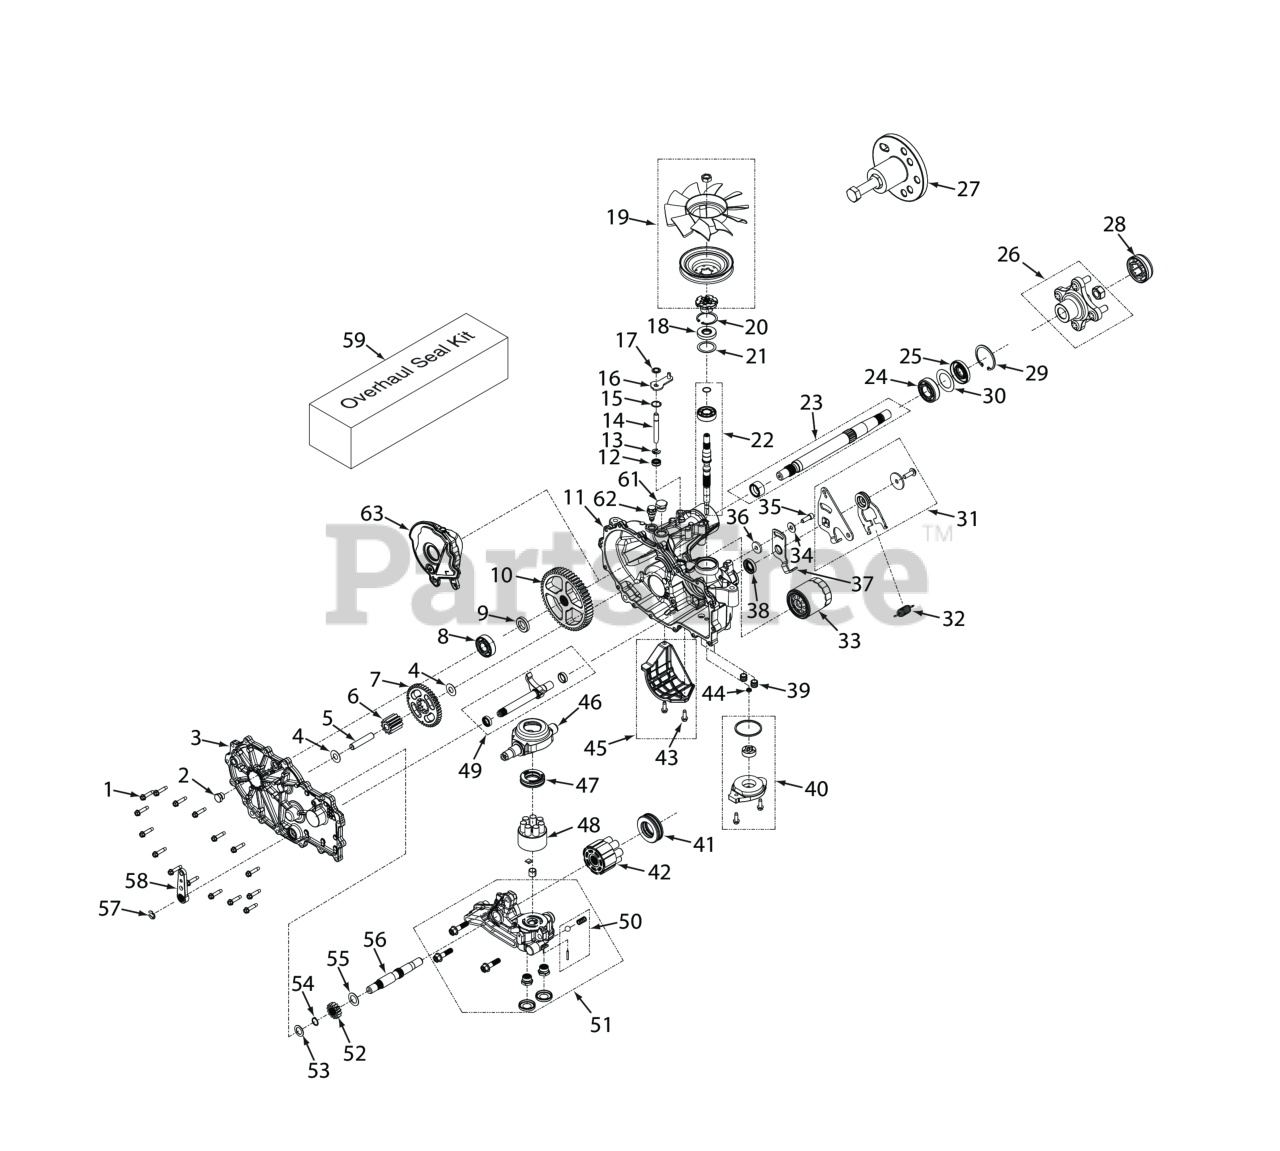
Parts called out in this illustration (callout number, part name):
1	Bolt, Hex Head 1/4-20 x 1-1/8"
2	Plug, External Hex Vent 9/16-18
3	Kit, Side Cover LH
4	Washer, .5 x 1.0 x .03
5	Jackshaft Pin
6	Gear, 11T
7	Gear, 45T
8	Kit, Bearing
9	Spacer, .750 x 1.320 x .257
10	Gear, 54T
11	Kit, Main Housing LH, Charge, Control
12	Seal, Lip, .375 x .75 x .25
13	Ring, .Retaining .375 External
14	Rod, By-Pass
15	R i n g , Retaining .750 Internal
16	Arm, Bypass (LH)
17	Ring, Retainging .375 External
18	Seal, Lip 17 x 40 x 7
19	Kit, Fan/Pulley
20	R i n g , Retaining 2.06 Internal
21	Washer, 1.23 x 1.56 x .04
22	Kit, Input Shaft
23	Kit, Shaft, Axle
24	Bearing, Ball 1.0 x 52 x 15 Open
25	Seal, Lip TC4 1.0 x 2.06 x .38
26	Hub, 4-Bolt
27	Kit, Hub Puller
28	Cap, Axle
29	R i n g , Retaining 2.06 Internal
30	Spacer, 1.355 x 2.035 x .021
31	Kit, RTN Bi-Directional (Right Side)
32	Spring, Extension, RTN - 44lbs
33	Filter, Oil
34	Washer, 7/16 x 7/8 OD x .06 HT
35	Bolt, Hex Head Cap Screw 5/16-24 x 1" Patch
36	Spacer, .32 ID x 1.005 OD x .1495 Thk
37	Arm, Neutral (Left Side)
38	Seal, Lip 18 x 32 x 7
39	Tube, Charge Triple O-ring
40	Kit, Charge Pump
41	Thrust Ball Bearing Assembly
42	Kit, 16cc Cylinder Block Assembly (steam
43	Bolt, 1/4-20 x 3/4"
44	Kit, Gerotor Seal
45	Kit, Filter Guard (LH)
46	Trunnion, Swashplate
47	Ball Thrust Bearing
48	Kit, Cylinder Block
49	Kit, Inboard, RH Rot B / LH Rot A (LH)
50	Kit, Charge Relief
51	Kit, Charge Relief
52	Washer, Flat, .71 x 1.16 x .04
53	Washer, HT .62 ID x 1.0 OD x .05 Thick
54	Ring, Retaining .625
55	Washer, .72 x 1.16 x .04
56	Shaft, Motor
57	Ring, Retaining External .375"
58	Handle, Brake
59	Kit, Seal (ZT-2800)
61	Plug, 3/4-16
62	Fitting 9 /16 - 18, Breather
63	Expansion Tank, Internal LH
